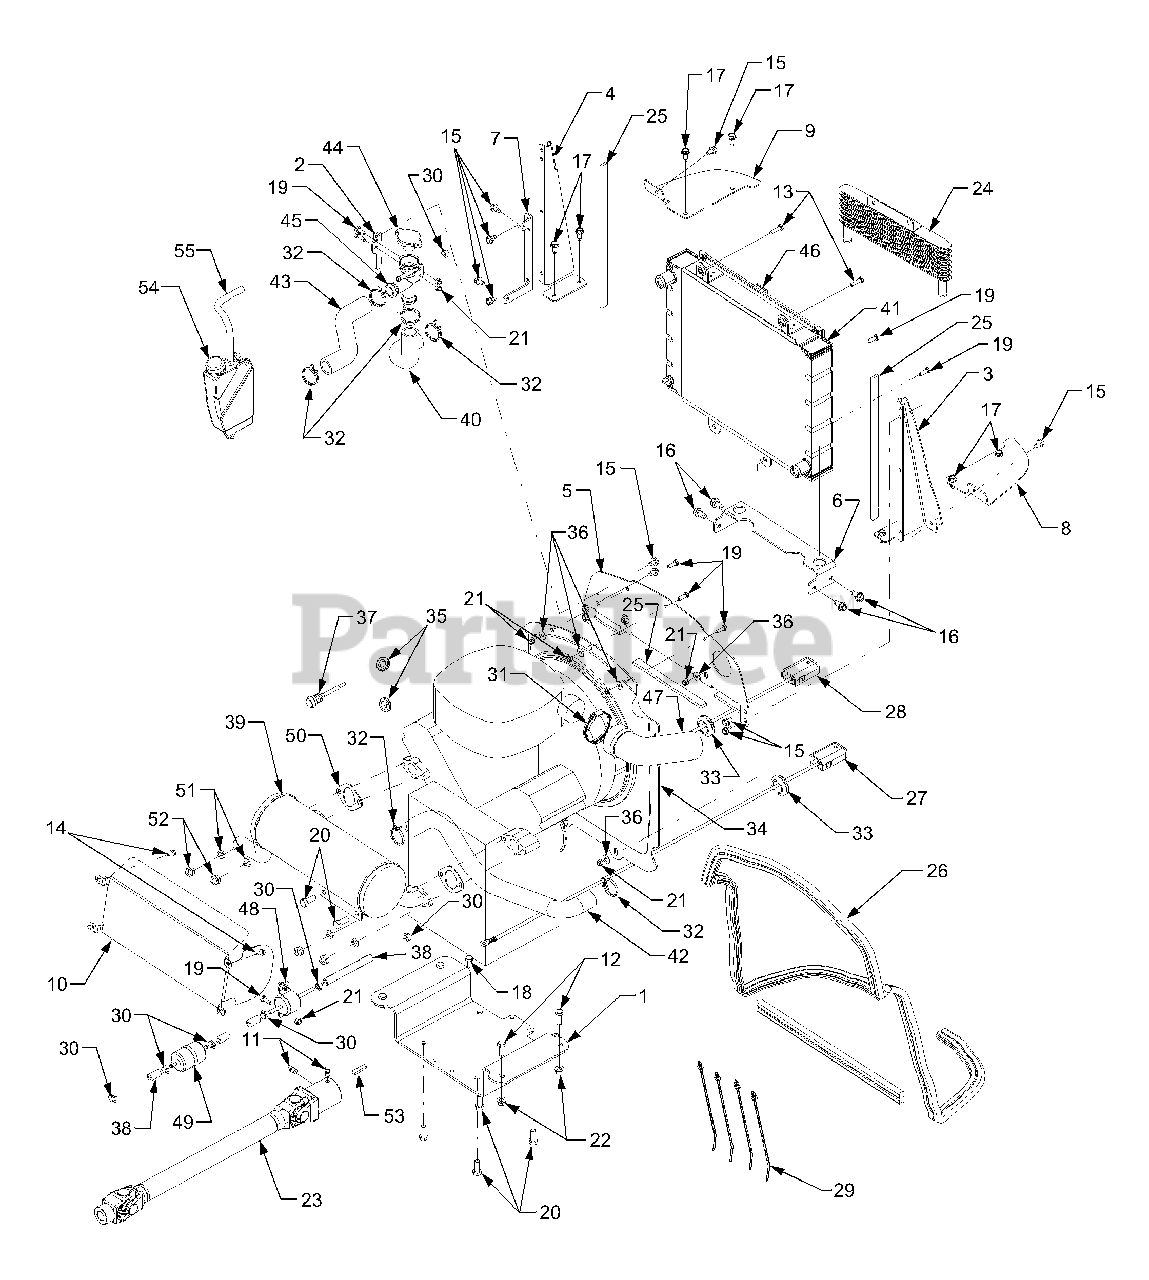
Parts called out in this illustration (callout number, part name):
1	Plate, Engine Mtg
2	Bracket, Filler Neck
3	Bracket, Radiator Mtg. RH
3	Graphic, Warning
4	Bracket, Radiator Mtg. LH
4	Graphic, Warning
5	Plate, Radiator Baffle
5	Graphic, Fan Warning
5	Graphic, Warning
6	Bracket, Radiator Mtg
7	Bracket, Ovrflw Bottle Mtg
8	Plate, Baffle RH
9	Plate, Baffle LH
10	Shield, Heat
11	Screw, Square Hd. Set, 3/8-16
12	Screw, Hex Cap, 3/8-16 x 1.0 GR5
13	Screw, Hex Cap, 1/4-20 x 1.0 GR5
14	Screw, Hex Wash Hd Tapp 1/4-20 x .5
15	Screw, Hex Wash Hd Tapp 5/16-18 x .5
16	Screw, Hex Wash Hd Tapp 3/8-16 x .75
17	Screw, Hex Wash Hd Tapp 5/16-18 x .75
18	Screw, Hex Cap, M8-20 x 16
19	Screw, Hex Cap, 1/4-20 x .75 GR5
20	Screw, Hex Cap, M10 x 1.5 x 25
21	Nut, Hex Nylon Insert Lock 1/4-20 GR8
22	Nut, Hx Flnge Lock, 3/8-16
23	Shaft, Drive
24	Cooler, Oil
25	Tape, Foam, .625 wide 42in.
26	Seal, Heat Baffle 96in.
27	Wire, Battery Neg
28	Wire, Battery Pos
29	Tie, Cable - Push Mount
30	Clamp, Hose
31	Clamp, Hose - Adjustable
32	Clamp, Hose
34	Shroud, Fan
36	Washer, Flat, .28 x .74 x .063
37	Cable, Choke Control
38	Fuel Line 5/16 ID 94in.
40	Hose, Filler to Radiator
42	Hose, Lower Radiator
43	Hose, Engine to Filler Neck
44	Cap, Remote Filler
45	Filler Neck, Remote Radiator
46	Screen, Radiator
47	Hose, Intake Air
49	Filter, Fuel
50	Gasket, Exhaust
51	Washer, Spring
53	Key, Crankshaft
54	Bottle, Over Flow
